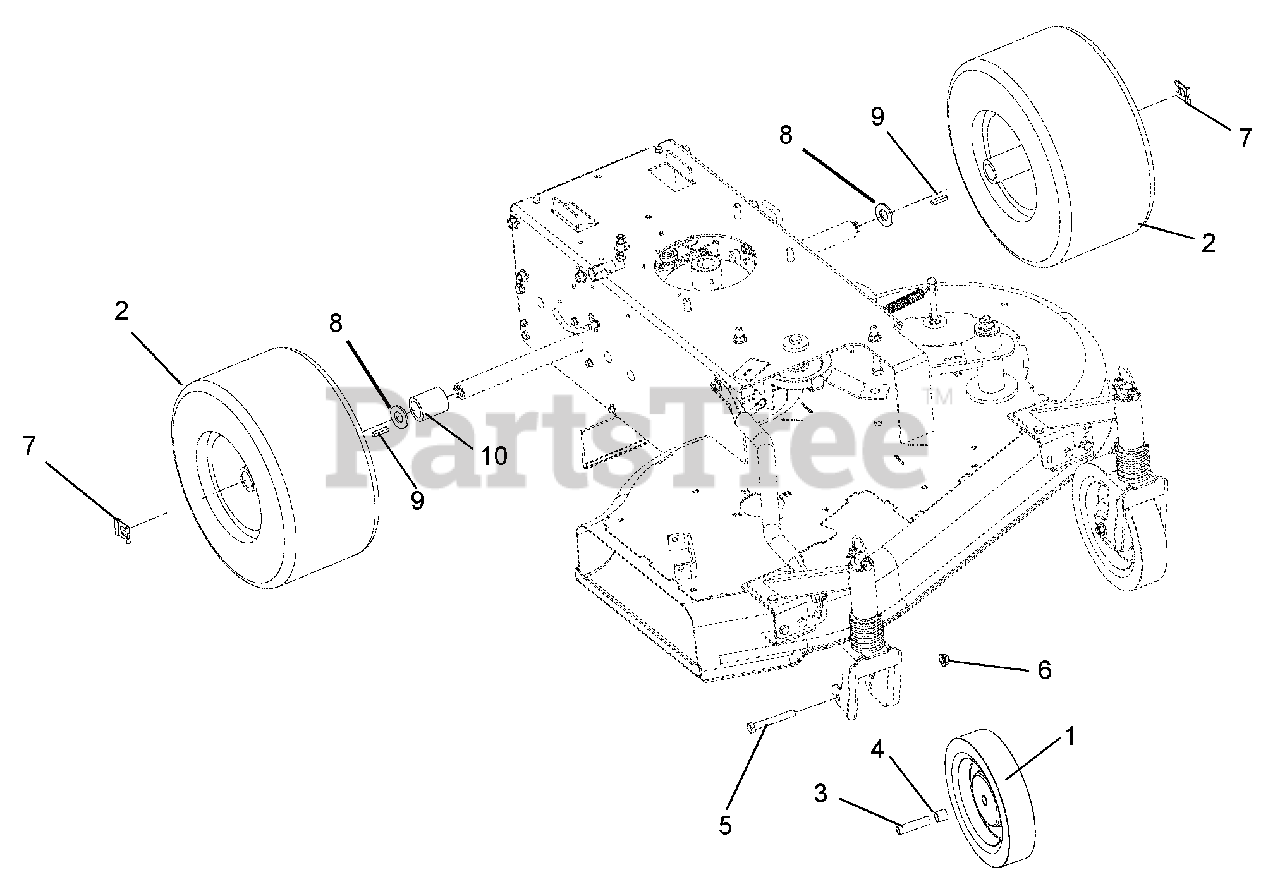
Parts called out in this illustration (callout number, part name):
1	Wheel, Diamond Tread 8.0 x 1.75 x .50
2	Assembly, Tire/Wheel 6 x 13
3	Spacer, Wheel
4	Spacer, Wheel
5	Bolt, Hex .38-16 x 2.75
6	Nut, Nyloc Flange .38-16
7	Clip, Snap .625 Diameter
8	Washer, Flat Steel .656 x 1.31 x .095
9	Key, Rectifier .25 x .188 x 1.00
10	Spacer 1.0 x 1.5 x 1.57
